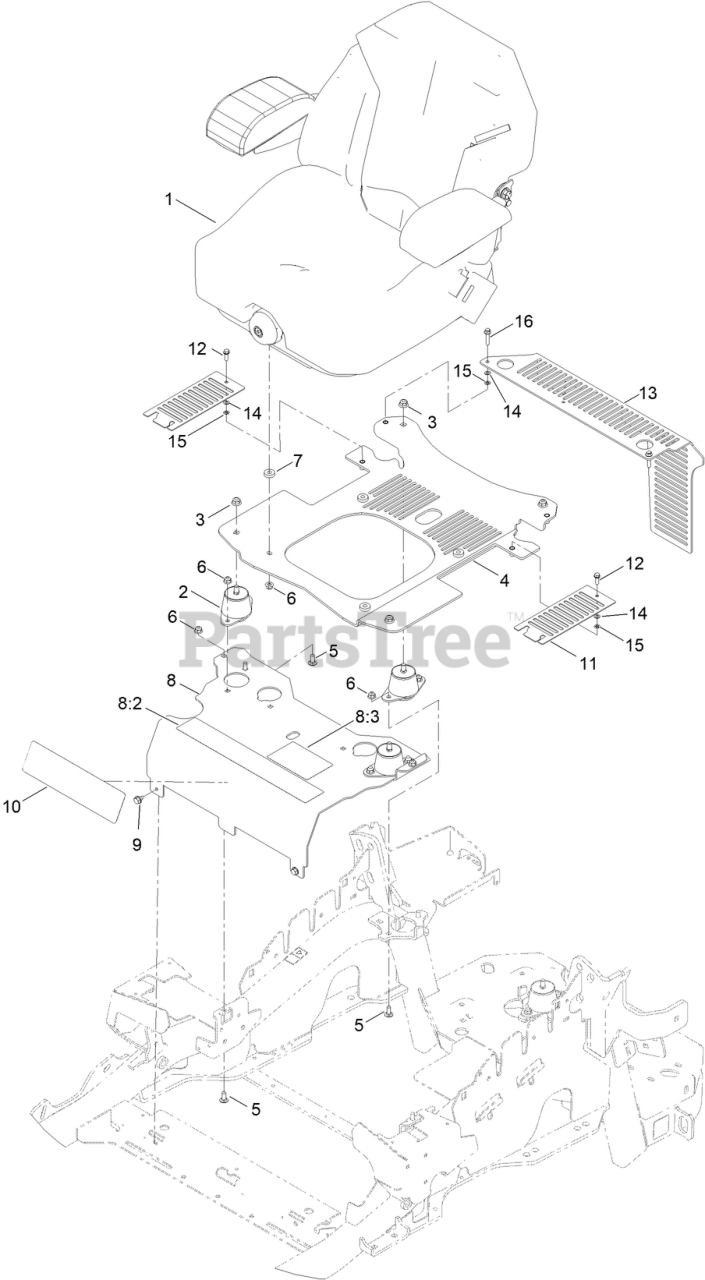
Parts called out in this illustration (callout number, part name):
1	SEAT-SUSPENSION
2	ISOLATOR-SEAT
3	NUT-HF, NI
4	SEAT BASE ASM
5	SCREW-CARR
6	NUT-HF, NI
8	MOUNT-SEAT
8:2	DECAL-CONSOLE
8:3	DECAL-SERVICE AID
9	SCREW
10	DECAL-CONSOLE
12	SCREW-HWH
13	GUARD-CE
14	WASHER-FLAT
15	PUSHNUT-RETAINER, BOLT
16	SCREW-HHF
